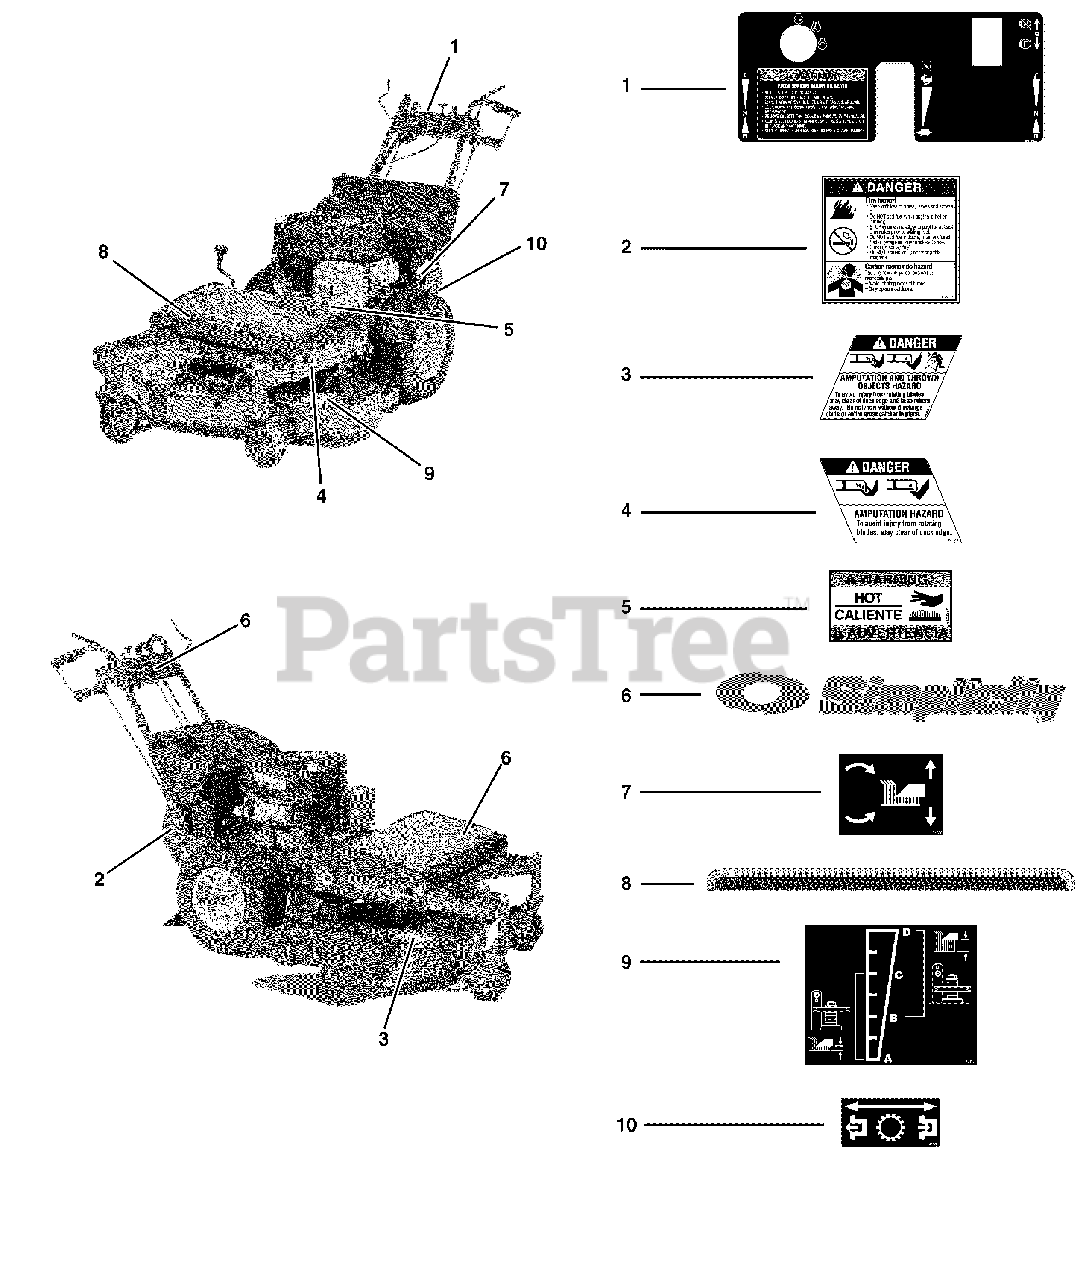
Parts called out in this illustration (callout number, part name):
1	DECAL, CONTROL PANEL
2	DECAL, DANGER
3	DECAL-DANGER DO NOT OPERATE W/O DEFLECTR
4	DECAL-DANGER DO NOT PUT HAND/FEET IN MWR
5	DECAL, WARNING, HOT
6	DECAL-SIMPLICITY SILVER & BLUE W/ICON
7	DECAL-CUT HEIGHT ADJUST HYDRO CUT
8	DECAL, STRIPE, SILVER & BLUE
9	DECAL, HEIGHT OF CUT
10	DECAL, HYDRO RELEASE
11	MODEL/SERIAL TAG
12	DECAL, OPEI
